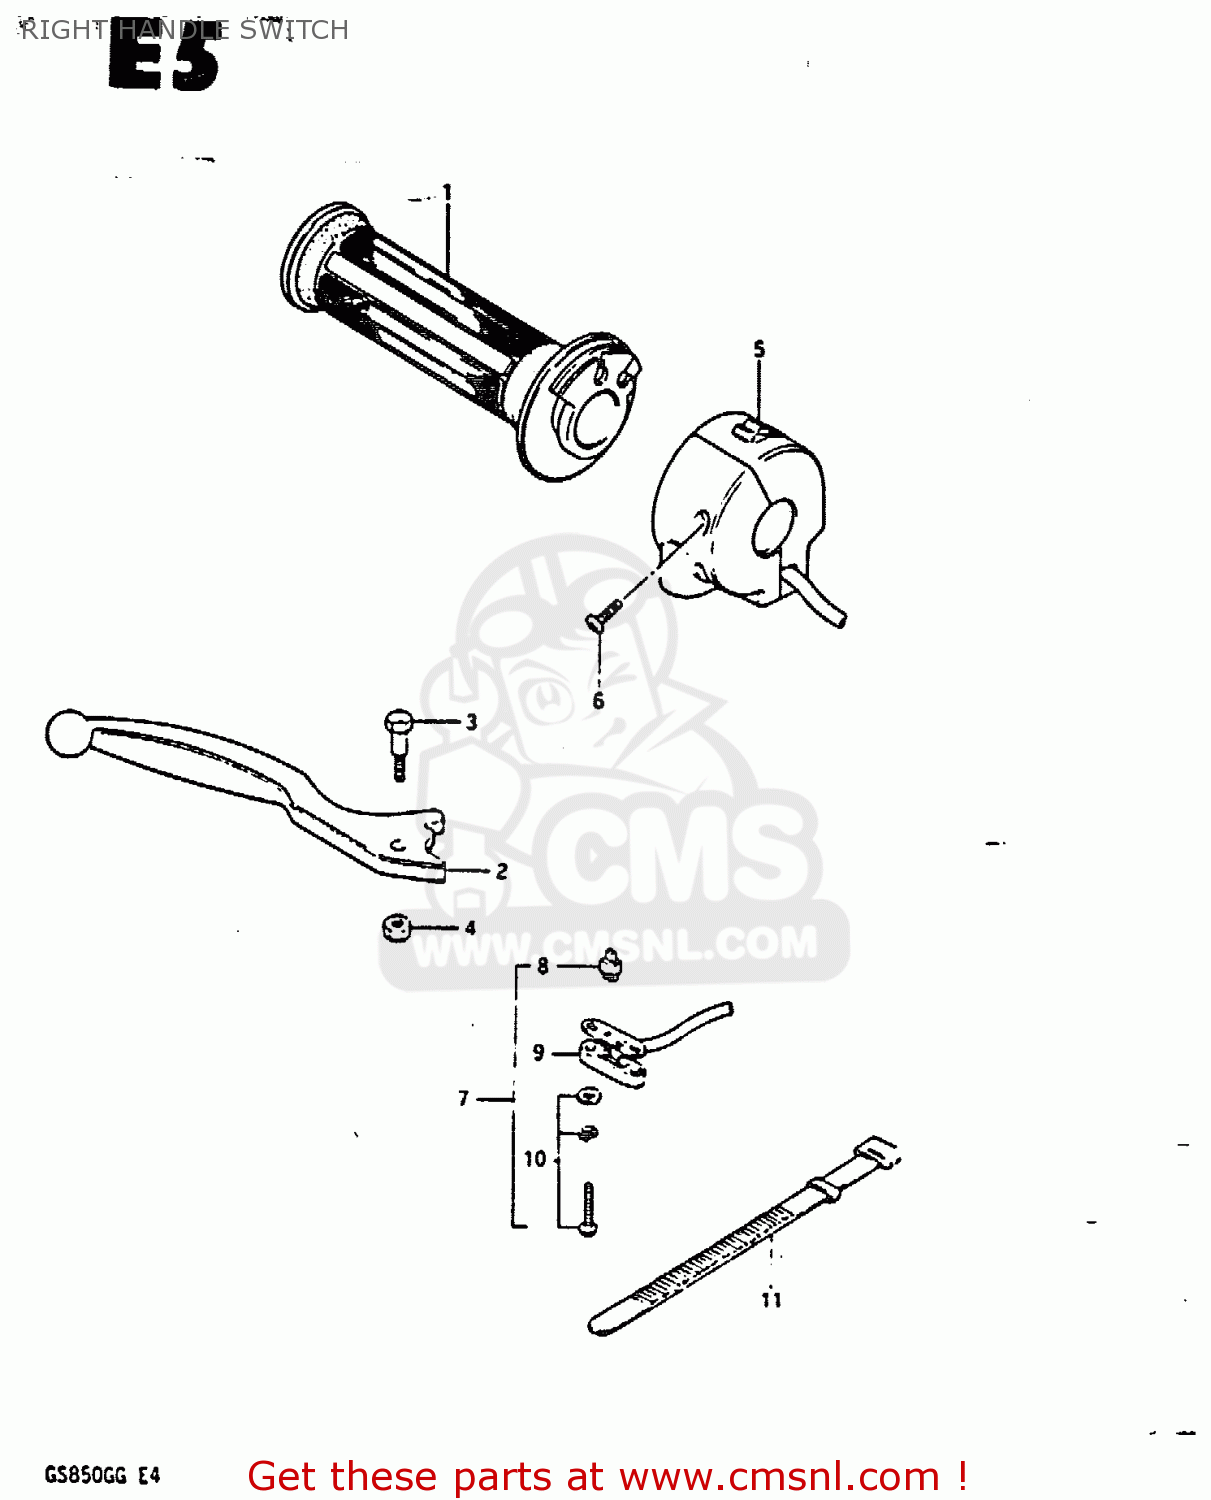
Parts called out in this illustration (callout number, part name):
1	GRIP,THROTTLE
2	BOLT
3	BOLT,LEVER PIVOT
4	NUT
5	SWITCH ASSY, HANDLE RH (FLAT)
6	SCREW
7	SWITCH ASSEMBLY
8	CONTACT,SWITCH
9	COVER,FR BK TERMINAL BASE
10	SCREW
11	CLAMP(L:120)
